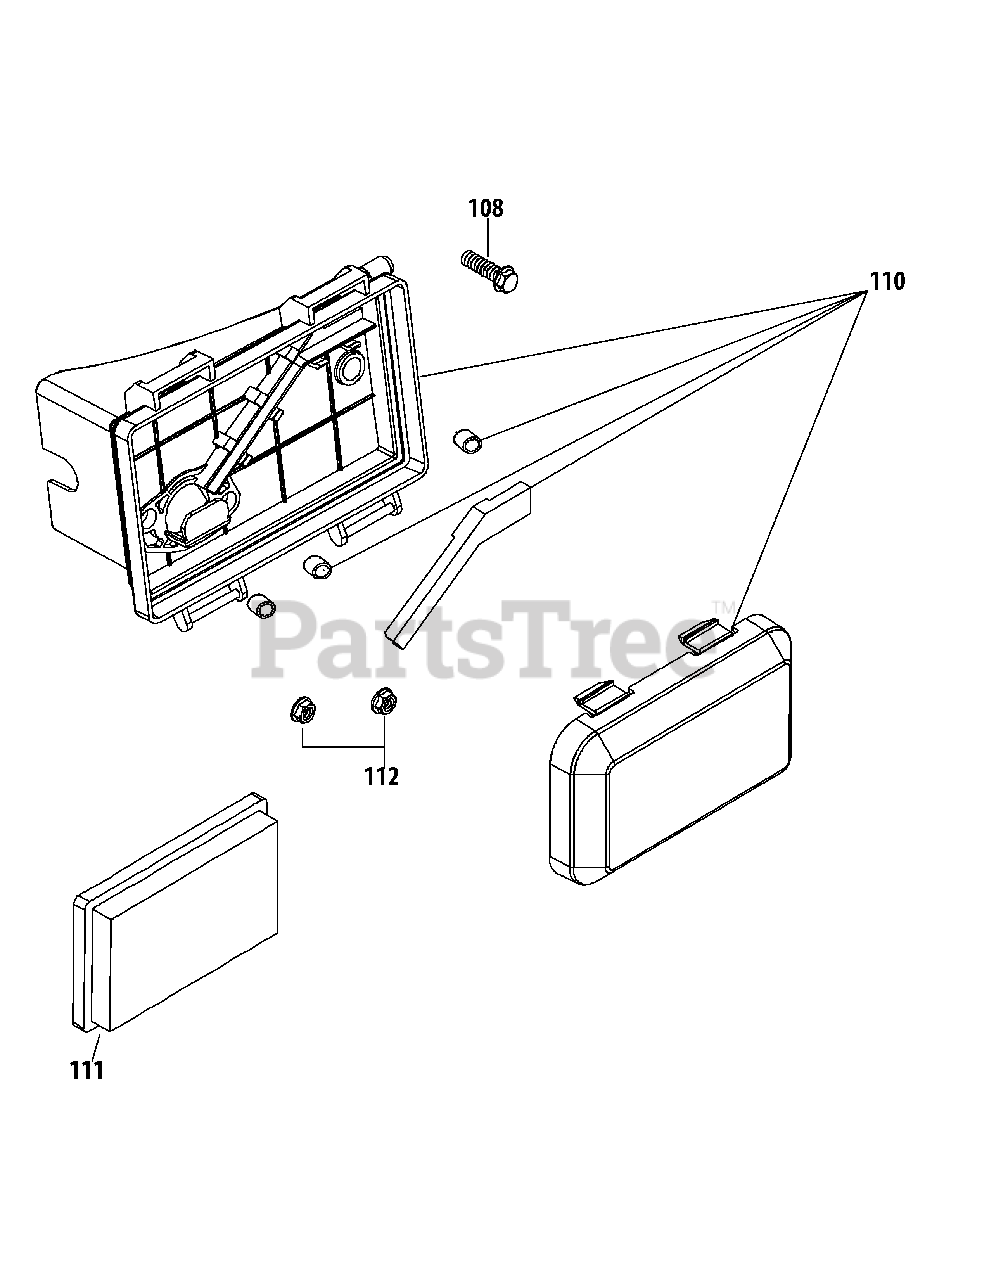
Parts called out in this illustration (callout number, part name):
108	Bolt M6X30 Af Base/Coil/E-Starter
110	Air Cleaner Housing Ass'Y
111	Air Filter Element, Paper
112	Nut M6X10Mm Starter/Carb/Muff
